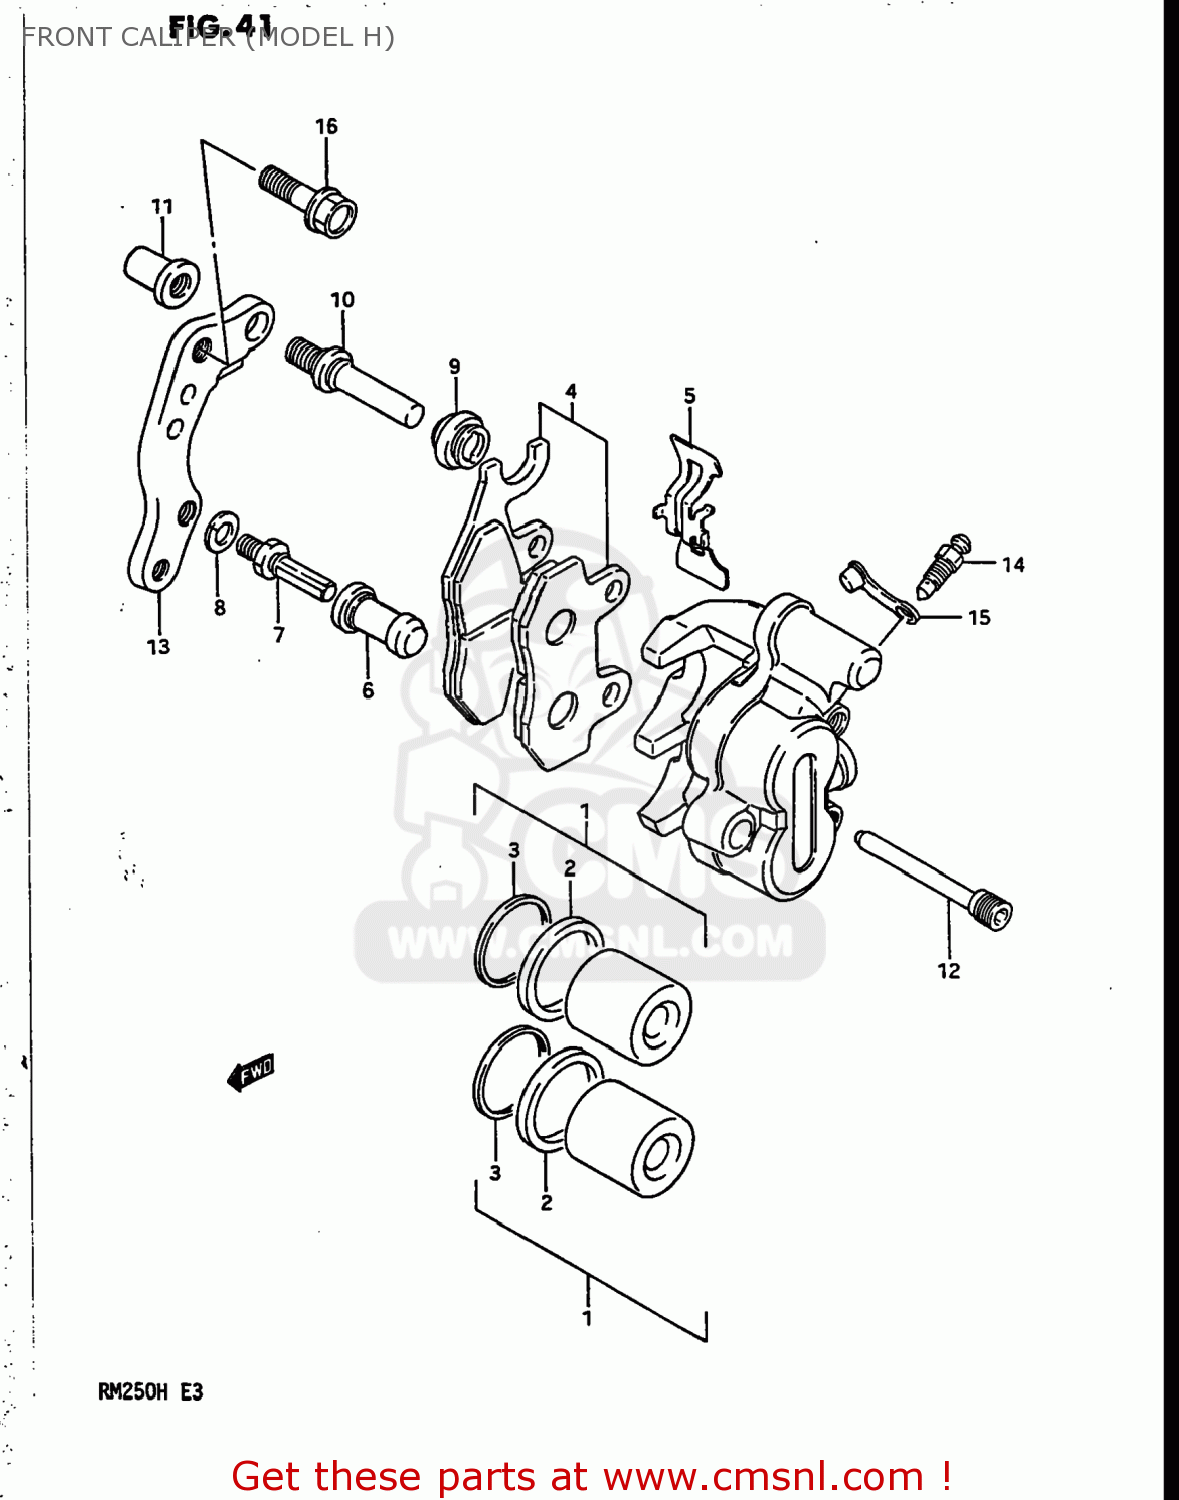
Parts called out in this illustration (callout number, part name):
1	CALIPER ASSEMBLY,FRONT,LEFT
2	SEAL,PISTON
3	SEAL,DUST
4	CALIPER ASSEMBLY,FRONT,LEFT
5	SPRING
6	BOOT
7	BOLT,PIN
8	WASHER,WAVE
9	BOOT
10	PIN,SLIDE
11	NUT
12	PIN,HOLDER
13	BRACKET
14	BLEEDER
15	CAP,BLEEDER
16	BOLT(8X24)
